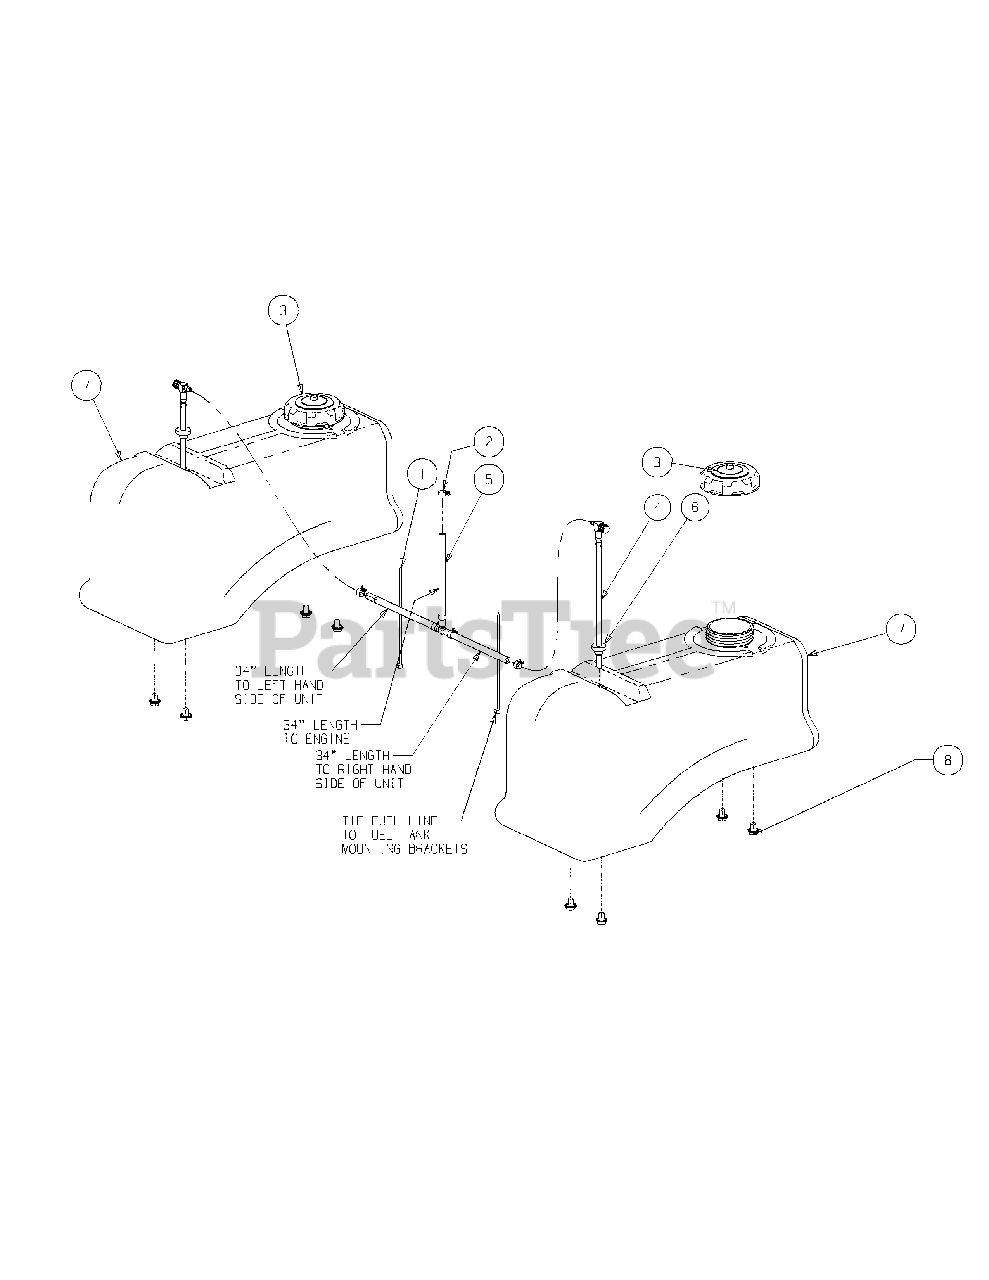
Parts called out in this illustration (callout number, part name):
1	Cable Tie
2	Hose Clamp, SAE #4: 1/4-5/8, SS
3	Fuel Cap, 3.5
4	Fuel Fitting
5	Fuel Hose Assembly includes:
5	Hose, 1/4" Fuel Line
5	Clamp, Union
5	Tee Fitting, Fuel
6	Grommet, Fuel Tank
7	Fuel Tank
8	Hex Cap Screw, 3/8-16 x .50 Flange Whiz
